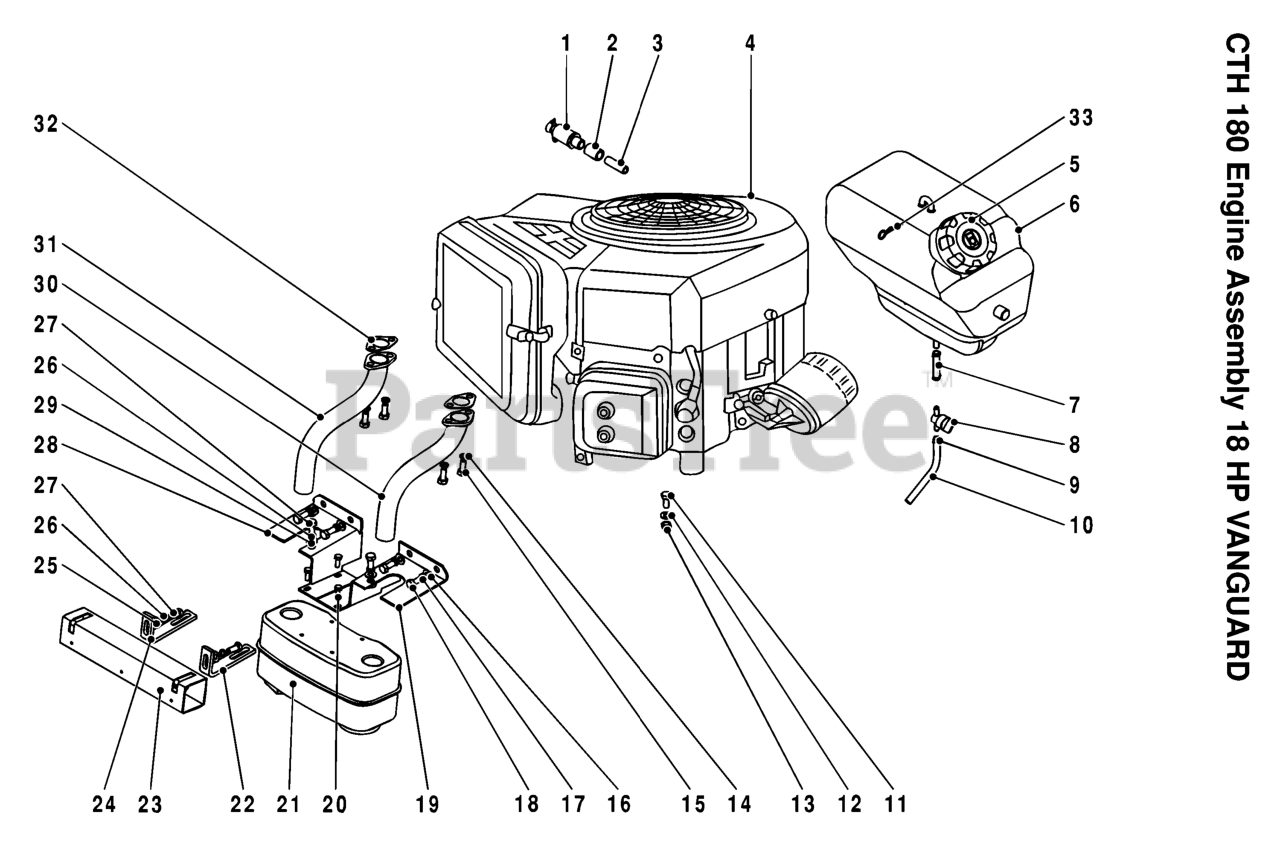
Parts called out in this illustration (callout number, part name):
12	SPRING WASHER
14	SPRING WASHER
17	SPRING WASHER
26	SPRING WASHER
